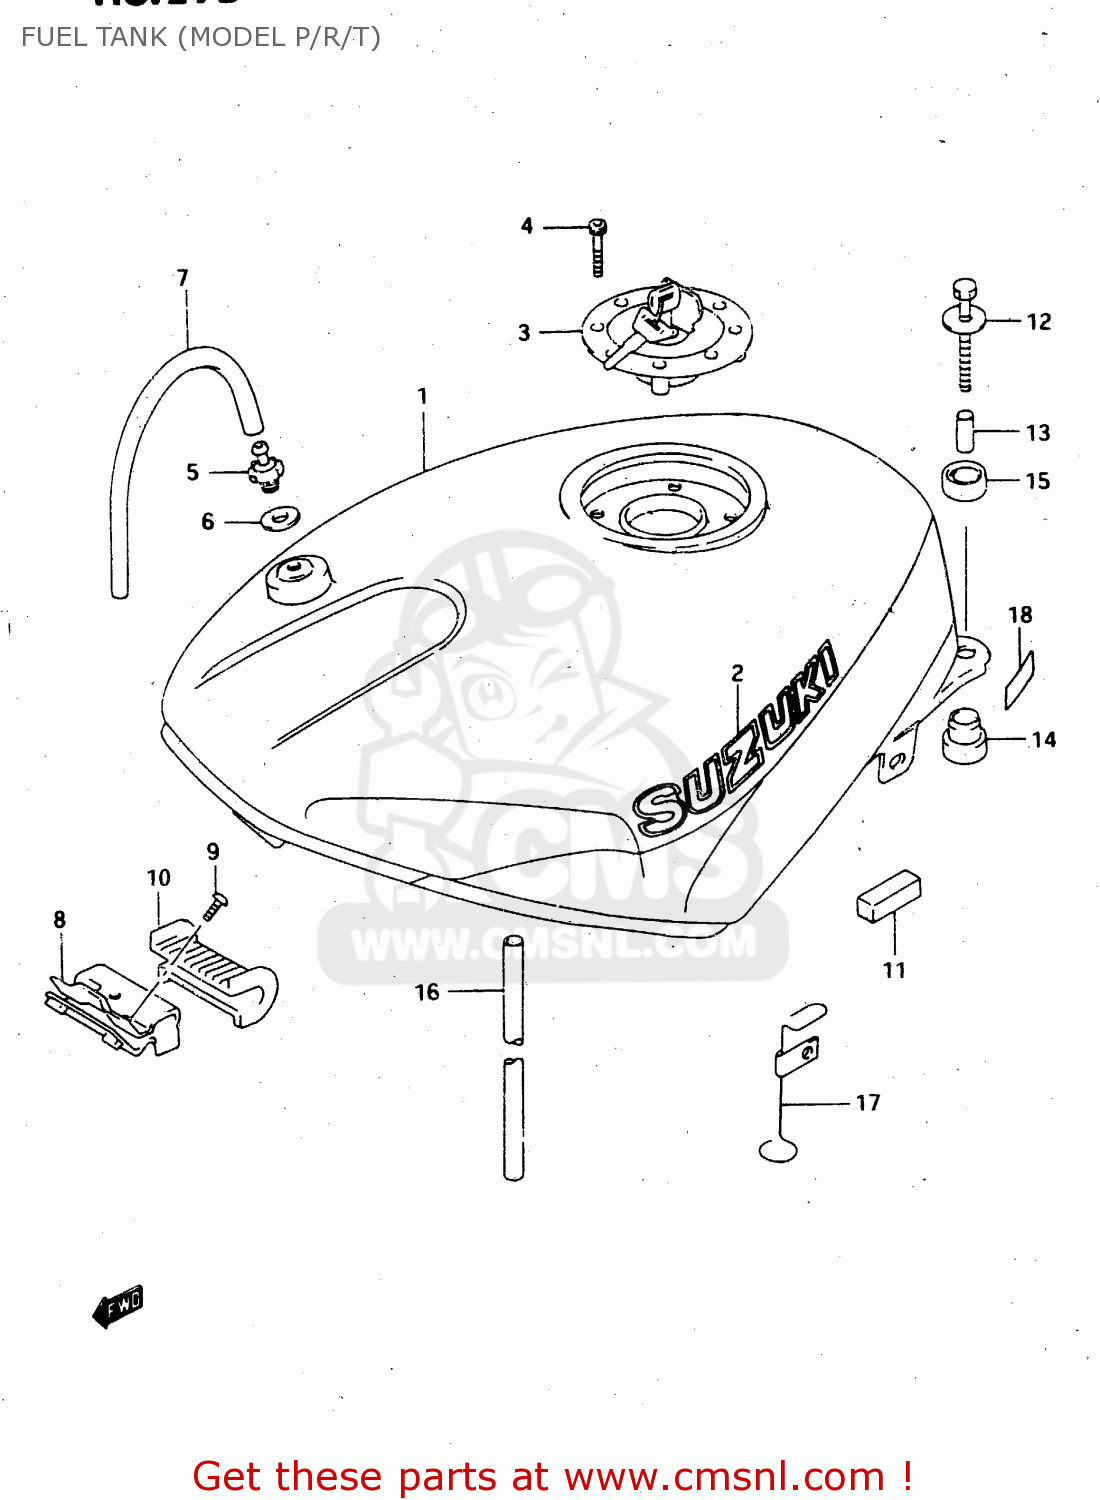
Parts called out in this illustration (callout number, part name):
1	TANK ASSY,FUEL
2	EMBLEM,FUEL TANK
3	CAP SET,FUEL TANK
4	BOLT(5X20)
5	PLUG,FUEL TANK BREATHER
6	GASKET(12.5X20X2.5) (NAS)
7	HOSE(5X8.2X600)
8	BRACKET,FUEL TANK
9	SCREW
10	CUSHION,FUEL TANK FR
11	CUSHION,FUEL TANK SIDE
12	BOLT
13	SPACER
14	CUSHION
15	CUSHION
16	HOSE(5X8.2X2000)
17	GUIDE, DRAIN HOSE
18	PROTECTOR,FRAME COVER NO.2
